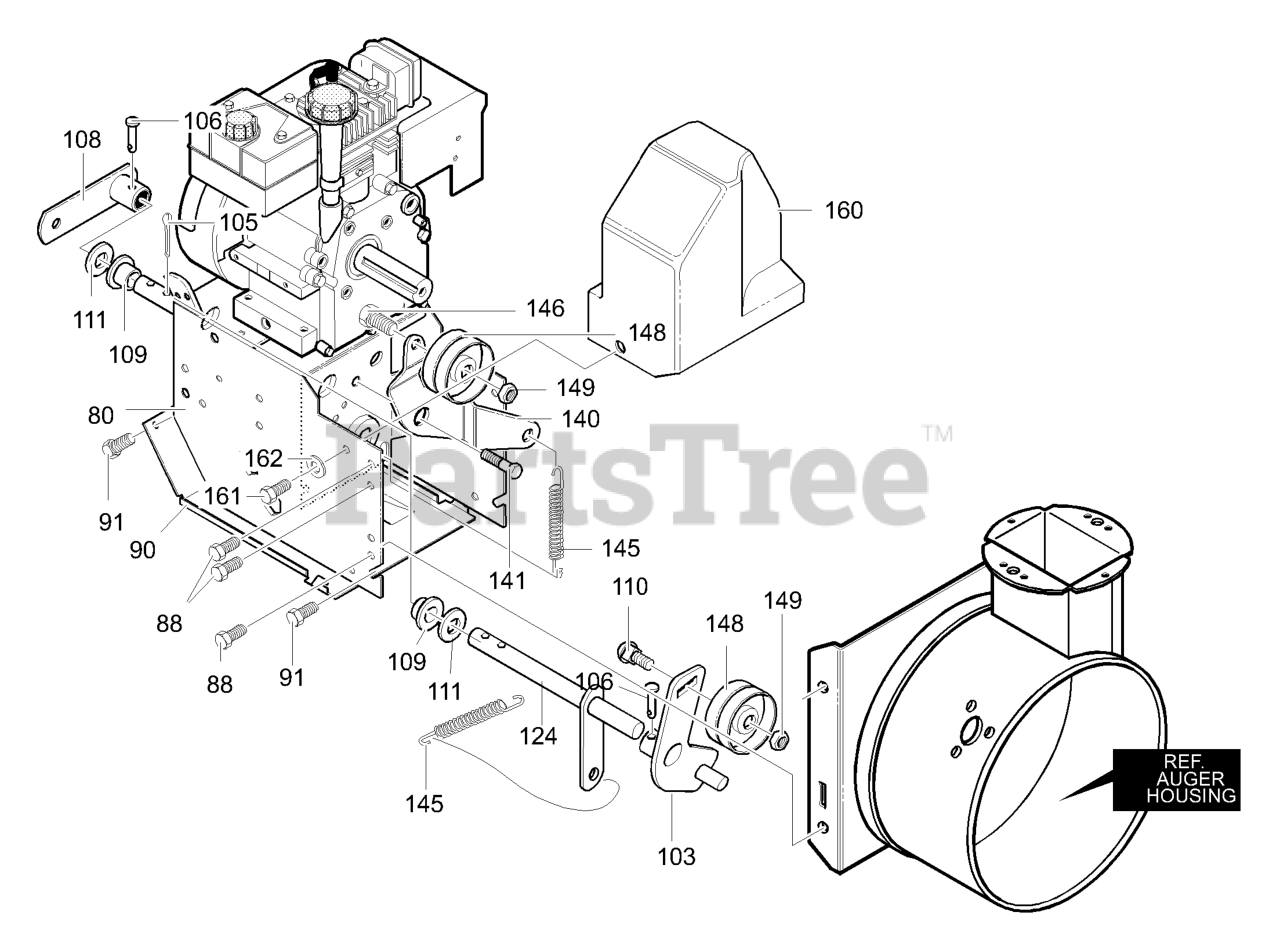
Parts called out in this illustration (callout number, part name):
80	FRAME, ASSY
88	SCREW, 5/16-18 x 0.50
90	COVER, BOTTOM
91	SCREW, 1/4-20X.63
103	ASSY., IDLER
105	HAIR PIN
106	CLIP, KLIK
108	ASSEMBLY, SPRING ATTACH WHEEL
109	BEARING, FLANGE
110	BOLT 3/8-16X1.25
111	FLATWASHER
140	LEVER, IDLER ARM TRACTION
141	BOLT, 5/16-18
145	SPRING, IDLER TRACTION DR
146	SCREW, 3/8-16 x 1.25
148	PULLEY, IDLER
149	NUT, 3/8-16
160	BELT COVER
161	SCREW, 1/4-20X.63
162	FLATWASHER
